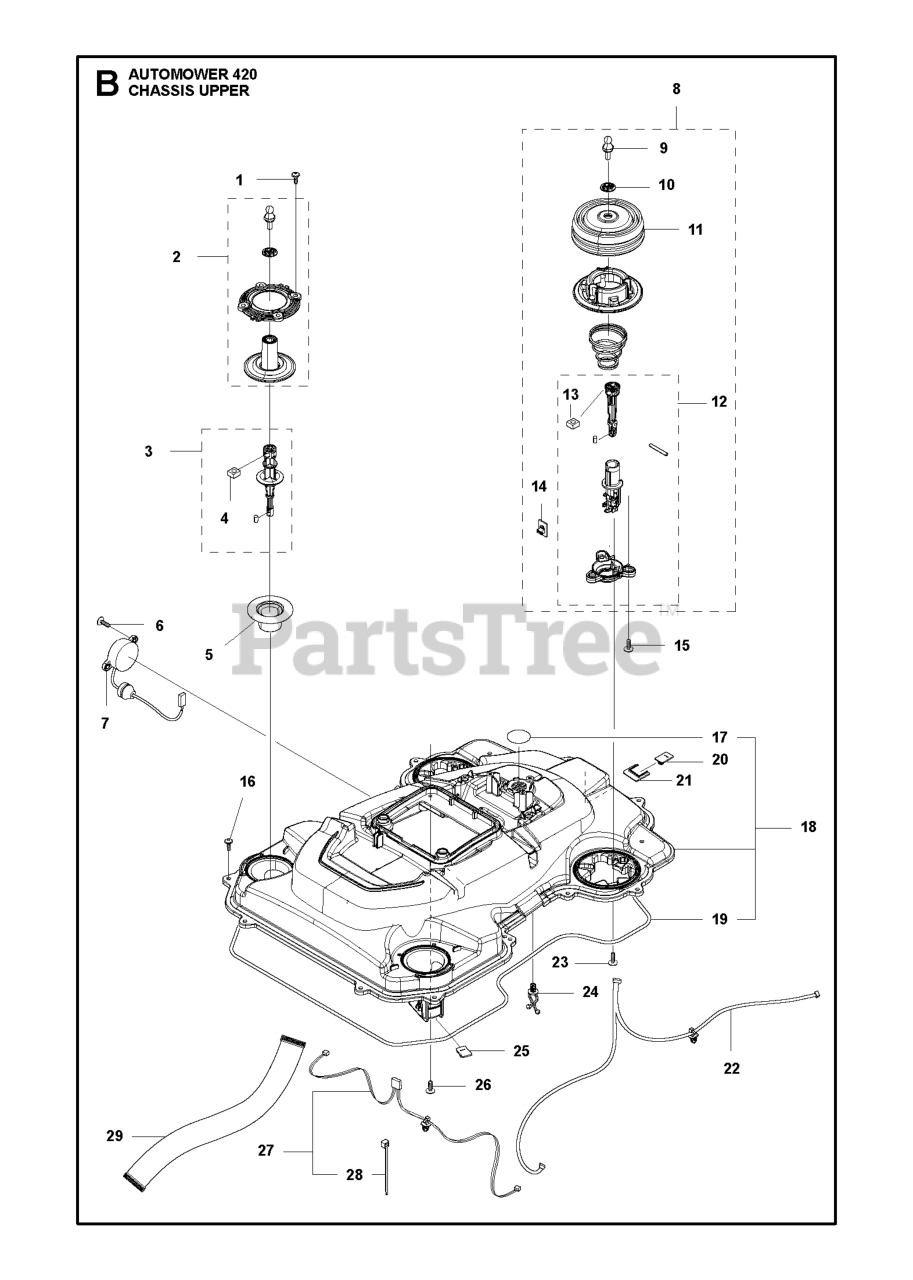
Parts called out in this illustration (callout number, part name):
1	SCREW ITXPANT
2	JOYSTICK KIT REAR
3	JOYSTICK KIT REAR
4	NUT
5	MOVEMENT LIMITER
6	SCREW 14MM
7	BUZZER ASSY
8	JOYSTICK KIT
9	STUD SNAPLOC
10	WASHER JOYSTICK
11	BELLOWS LIFT-COLLISION
12	JOYSTICK KIT
13	NUT
14	PRINTED CIRCUIT ASSY PCBA LIFT
15	SCREW 14MM
16	SCREW ITXPANT
17	KIT AIR FILTER KIT 305 - 10 PC
18	CHASSIS KIT UPPER
19	SEALING STRIP
20	PRINTED CIRCUIT ASSY COLLISION
21	CLIP COLLISION BOARD
22	1OOM KIT COLLISION SENSOR
23	SCREW ITXPANT
24	HOLDER TWIST LOCK
25	PRINTED CIRCUIT ASSY COLLISION
26	SCREW 14MM
27	LOOM KIT LIFT SENSOR
28	BAND
29	LOOM MMI
